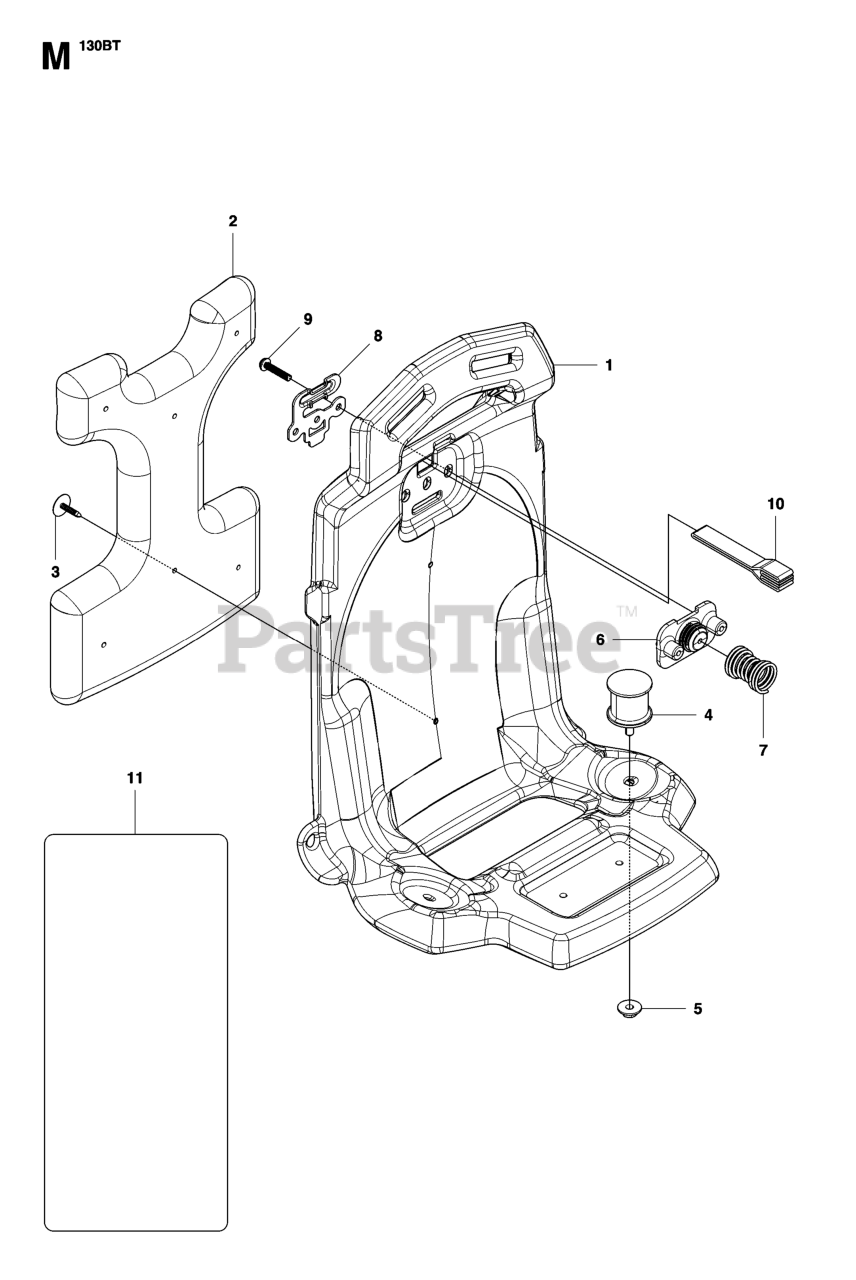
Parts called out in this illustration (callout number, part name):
3	CLIP
4	DAMPER
5	NUT (M6)
9	SCREW
11	LABEL, CAUTION
